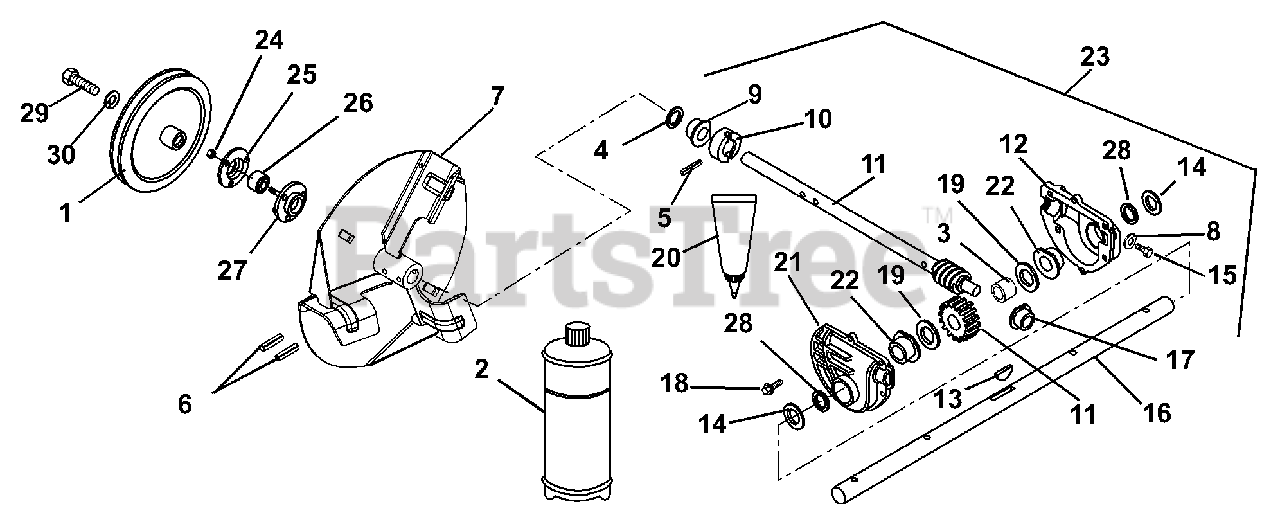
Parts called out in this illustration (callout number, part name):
1	PULLEY, 4L W/HUB, .75 X 8.5
2	ARIENS 16 OZ.BOTTLE OF L2 LUBE
3	BSHG-SLV .755X1.500X.442
4	SEAL-OIL.748X1.378X.276 RBR OD
5	@PIN-GRV .188X1.25 TP E ALLOY
6	PIN-ROLL .250X1.75
7	WELDMENT, IMPELLER,12" 3 BLADE
8	WSHR-FIBER .437X.656X.032
9	BSHG-FLG .750X1.000X.750X1.250
10	THRUST COLLAR, .75" ID
11	SHAFT AND WORM GEAR ASSEMBLY
12	GEARCASE CASTING, MACHINED LH
13	KEY-WDRF .19X.63 HRD #61
14	@WSHR-FL-STL.812X1.50X.135YWZC
15	SCR-TAP .38-16X.75 ROLOK YZ WX
16	SHAFT, RAKE - 20" (.750 DIA)
17	BSHG-FLG .502X1X.750
18	@SCR-TAP .25-20X1.00 HWH TR YZ
19	WSHR-FL-STL.755X1.375X.062YWZC
20	LOCTITE 518 GASKET--6ML TUBE
21	GEARCASE CASTING, MACHINED RH
22	BSHG-FLG .753X1.127X.500X1.501
23	GEARCASE, 20" ALUM, SMALL CD
24	@NUT-LK-CTR .25-20 YWZC
25	BEARING FLANGE
26	BRG-BALL .750X1.750X.50
27	BEARING FLANGE
28	SEAL-OIL .750X1.375X.250
29	BLT-HEX .31-24X.75 YWZC GR5
30	WSHR-LK .312X.097 HVY YWZC
